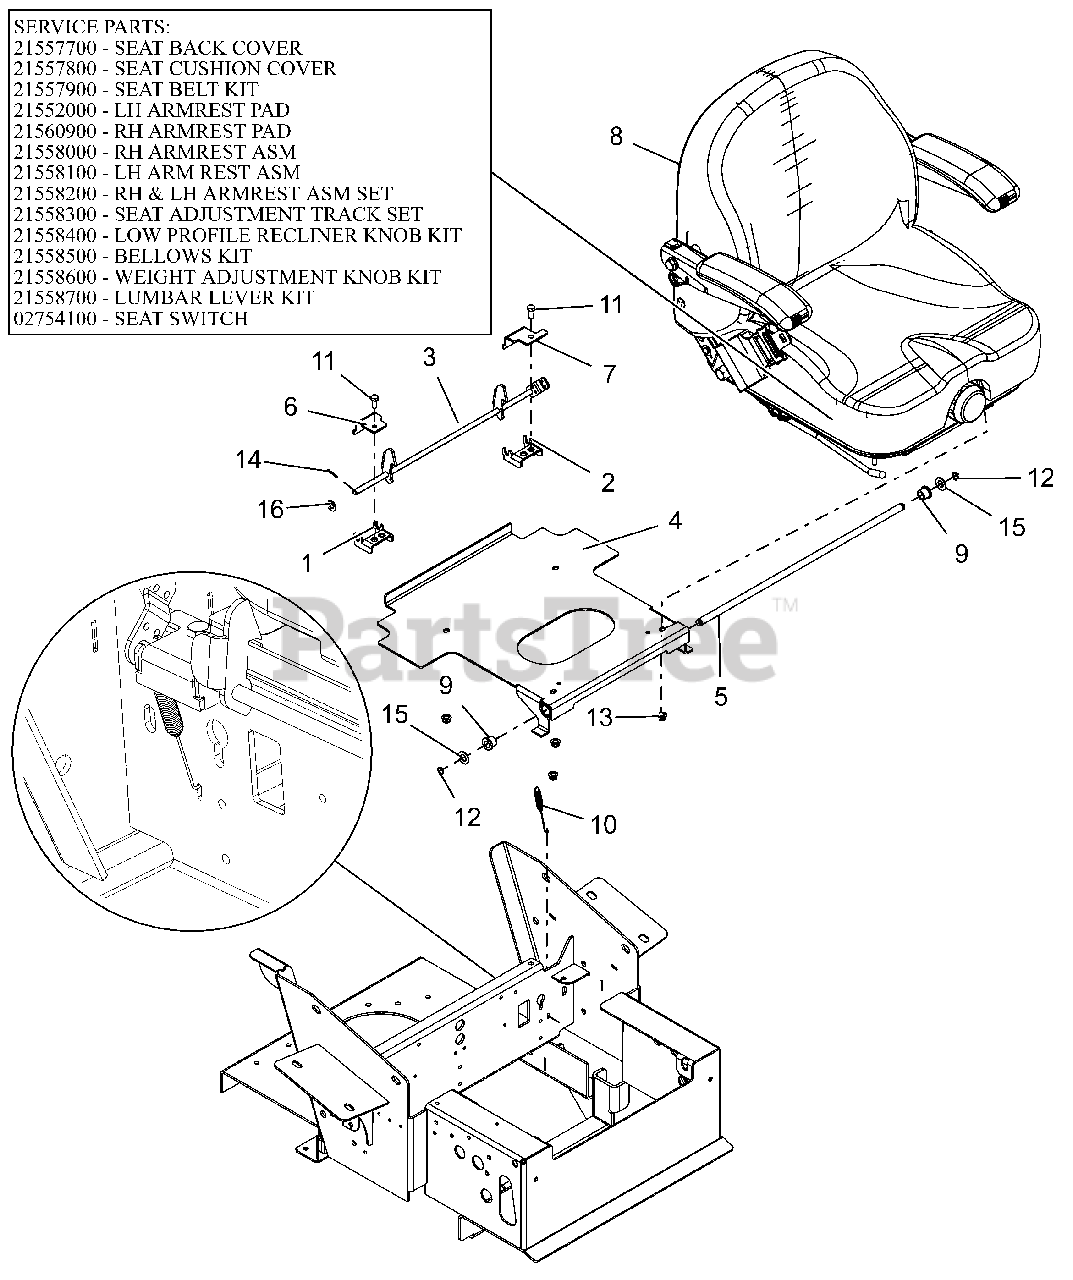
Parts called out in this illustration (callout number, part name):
1	PT100 RH SEAT LATCH MNT WMT-BL
2	PT100 LH SEAT LATCH MNT WMT-BL
3	PT100 SEAT LATCH WLDMT - BLACK
4	PT100 SEAT PLATE WLDMT - BLACK
5	SHAFT, PT100 SEAT PIVOT
6	PT100 RH TOP SEAT LATCH MNT-BL
7	PT100 LH TOP SEAT LATCH MNT-BL
8	SEAT, FULL SUSPENSION
8	COVER, SEAT BACK
8	COVER,SEAT CUSHION
8	KIT, SEAT BELT
8	PAD, ARMREST
8	PAD, ARMREST (HARD)
8	ARMREST, RH ASSEMBLY
8	ARMREST, LH ASSEMBLY
8	SET, RH & LH ARMREST ASSEMBLY
8	SET, SEAT ADJUSTMENT TRACK
8	KIT, LOW PROFILE RECLINER KNOB
8	KIT, BELLOWS
8	KIT, WEIGHT ADJUSTMENT KNOB
8	KIT, LUMBAR LEVER
8	SWITCH- SNAP MTG N.O.
9	BSHG, FLG .516X.750X.625X.937
10	SG-TENS .043X.44X3.31 WLD 5.8
11	@BLT-HEX .31-18X.75 GR5 YWZC
12	RG-RTNG-EXT .500X.050 (SNAP)
13	@NUT-LK-NYL-FLG .31-18 YWZC
14	@PIN-CTR .09X.75 EXTPRSQCT YWZ
15	WSHR-FL-STL.531X1.00X.063 YWZC
16	@WSHR-FL-STL.406X.812X.065 YWZ
